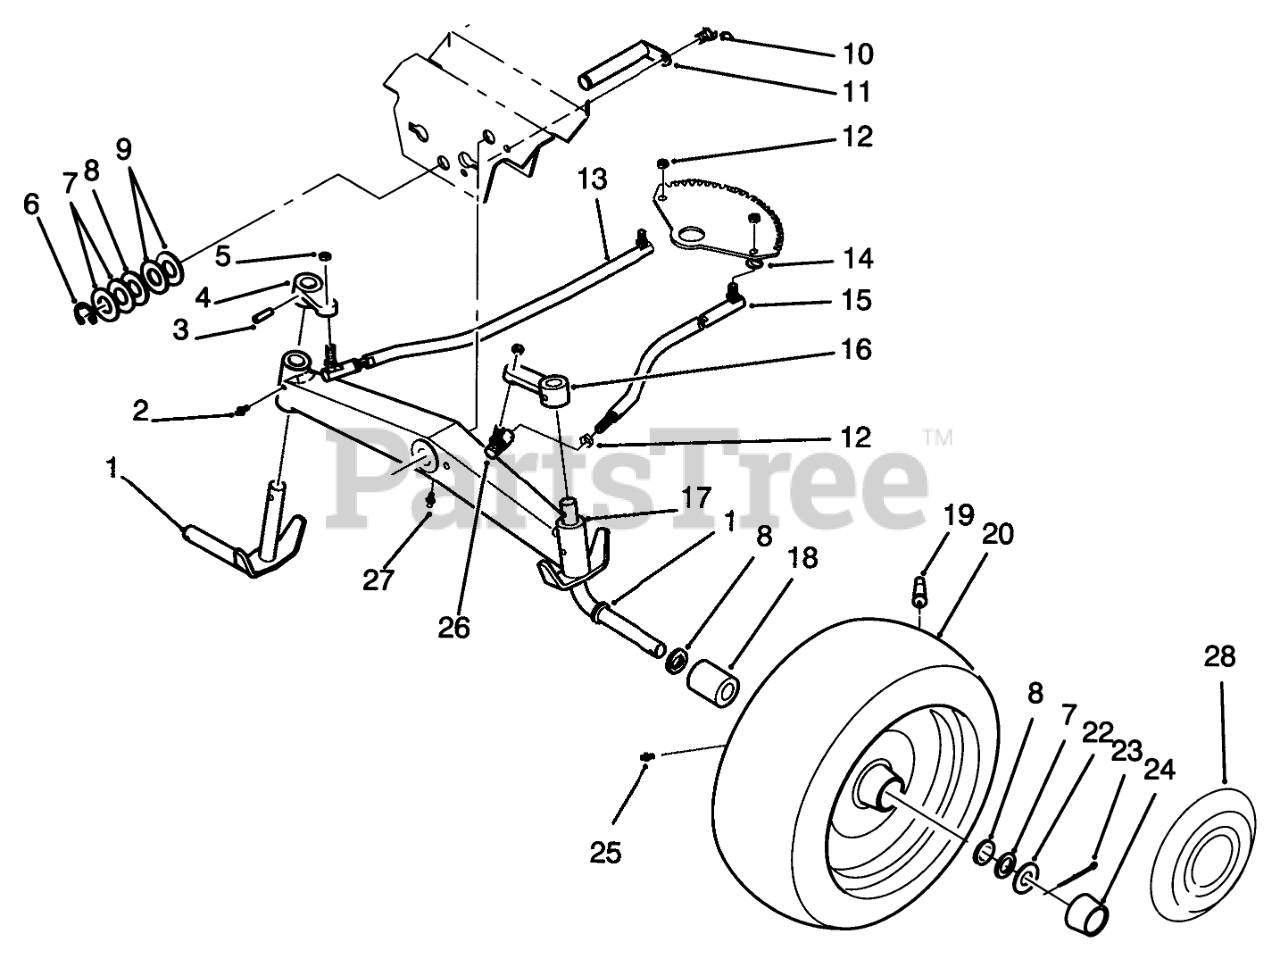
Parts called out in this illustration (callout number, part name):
1	Spindle
2	FITTING-GREASE
4	Arm-Spindle, R.H.
5	Nut
6	E-RING
7	WASHER-SHIM
8	WASHER
9	WASHER
10	Bolt
11	WLDMT-AXLE PIN R
12	NUT-6
13	Ball Joint
14	Collar
15	Steering Link Rod, L.H.
16	Arm-Spindle, L.H.
17	Axle-Front
18	BEARING-WHEEL
19	VALVE
20	Tire (16 x 6.5-8) 2-Ply -2 Wheel Axel
22	WASHER WHEEL
23	PIN-COTTER
24	HUBCAP
25	ZERK-GREASE
26	ASM-Rod
27	FITTING-GREASE
28	8"-HUB CAP LOGO
